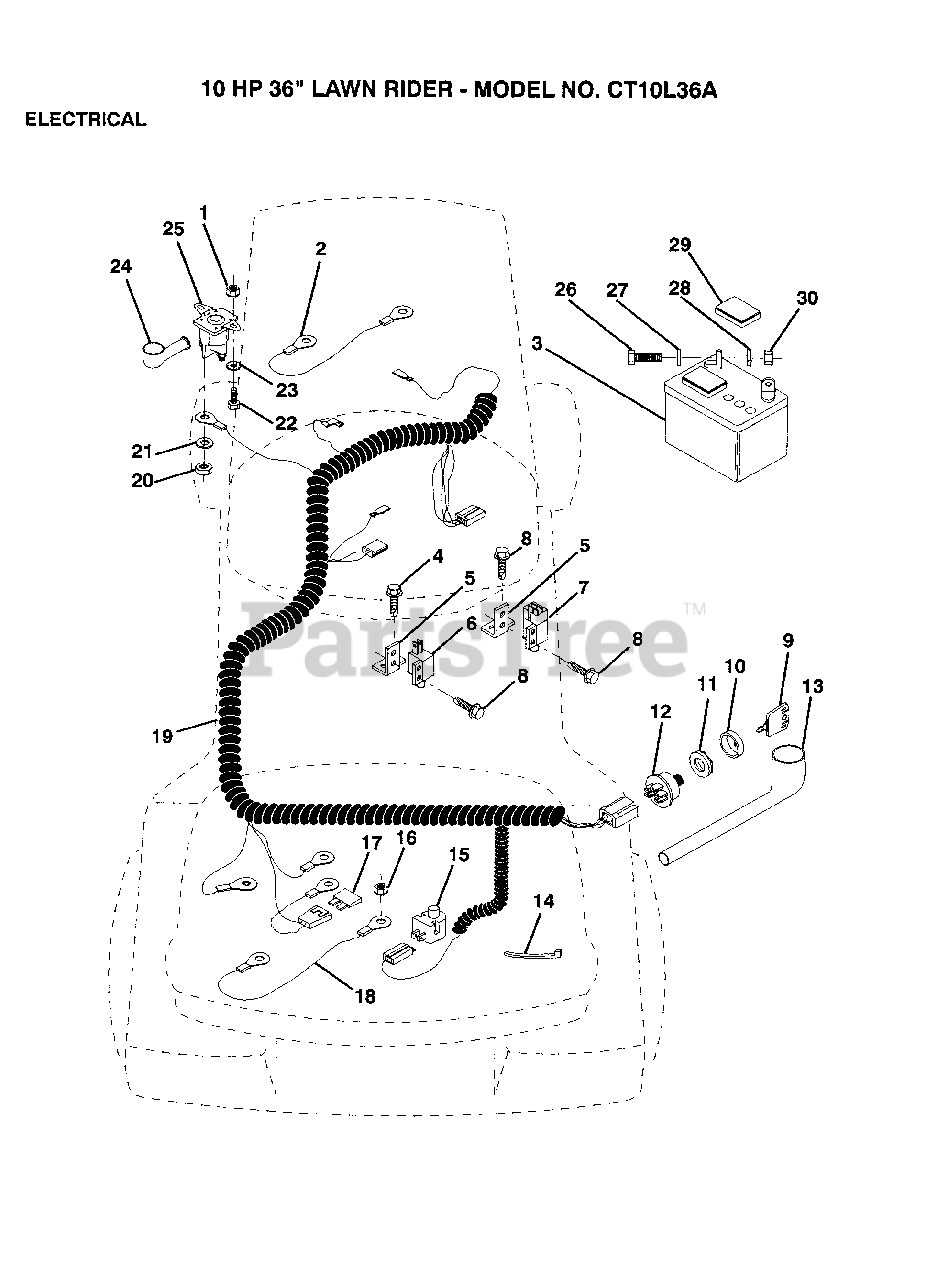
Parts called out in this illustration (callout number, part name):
1	NUT
2	CABLE ASM.
4	SCREW
5	BRACKET LT
6	SWITCH-INTER. GT
7	SWITCH INTERLOCKT
8	SCREW
9	KEY
11	NUT IGNITION
13	COVER IGNITION SW
14	WIRE TIE
15	SWITCH SEAT
17	FUSE HYT
18	CABLE ASSY
20	NUT
22	BOLT
26	BOLT LT
27	WASHER
28	LOCKWASHER
29	"CAP,BATTERY "
